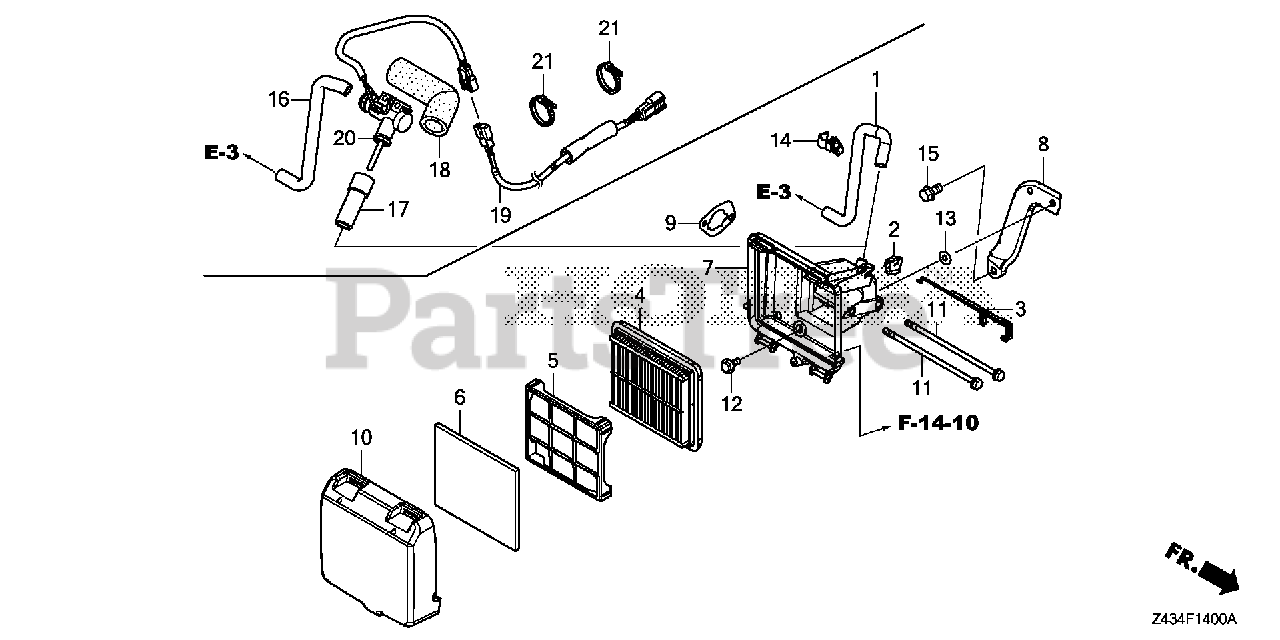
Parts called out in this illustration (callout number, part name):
1	TUBE, BREATHER
2	GROMMET, CHOKE ROD
3	ROD, CHOKE
4	ELEMENT, AIR CLEANER (WIX FILTERS)
5	GRID, AIR CLEANER
6	FILTER (OUTER) (WET)
7	HOUSING, AIR CLEANER *NH1* (BLACK)
8	STAY, AIR CLEANER
9	GASKET, AIR CLEANER
10	COVER, AIR CLEANER *NH1* (DUAL) (BLACK)
11	BOLT, FLANGE (6X140)
12	BOLT, TOP COVER
13	WASHER, AIR CLEANER
14	CLIP, VENT RETURN
15	BOLT, FLANGE (8X16) Use from Engine SN 1000016.
